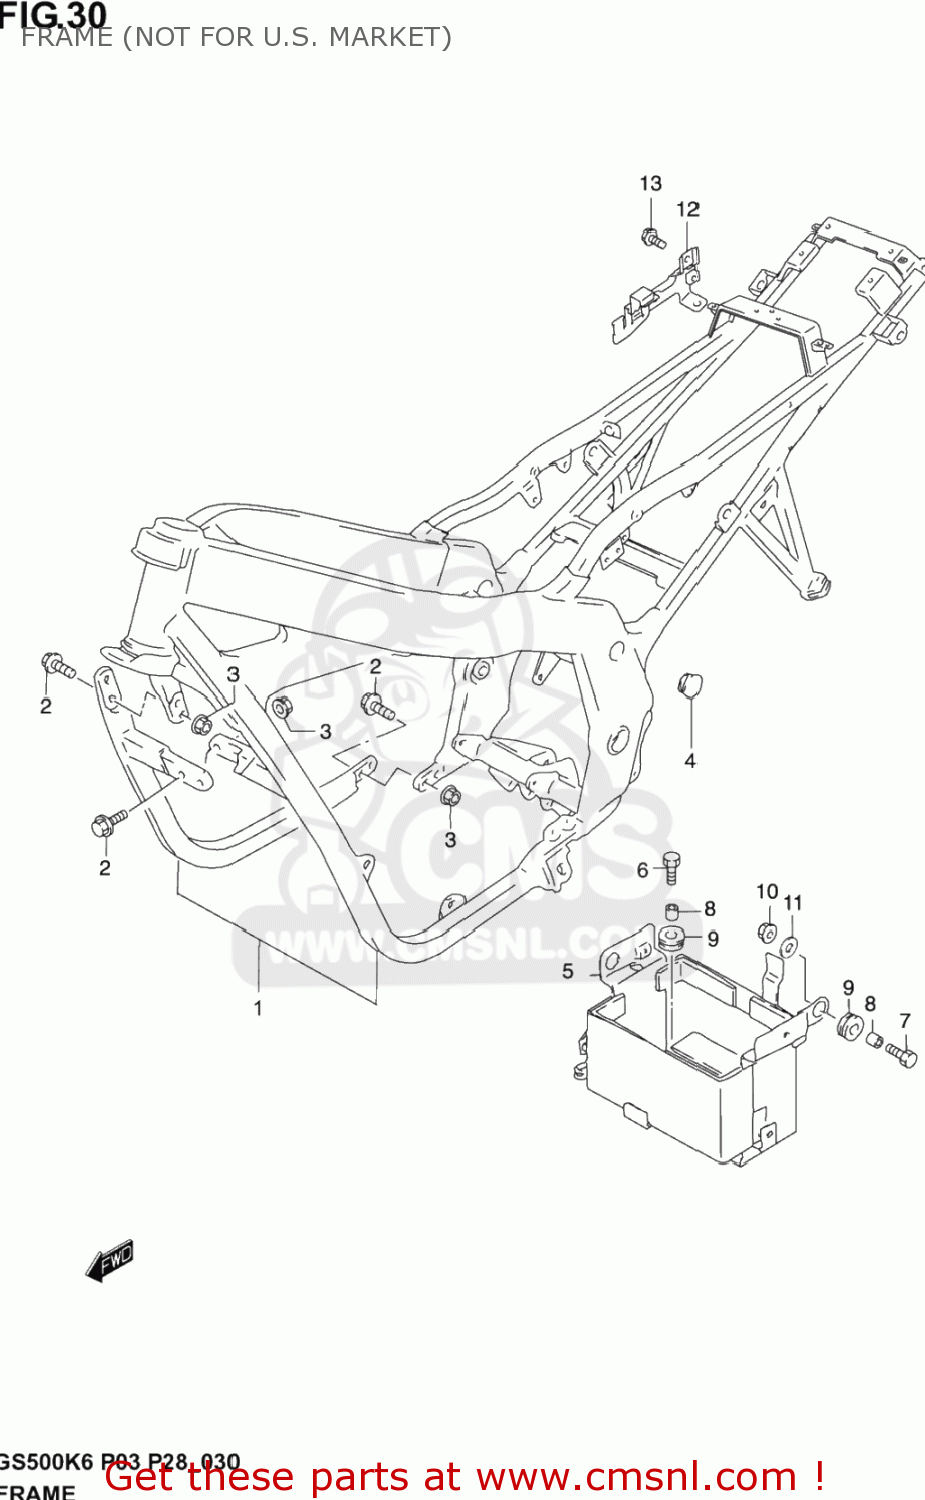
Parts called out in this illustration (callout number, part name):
1	FRAME SET(SILV
2	BOLT
3	NUT
4	CAP,BODY FRAME
5	HOLDER,BATTERY
6	BOLT 6X16
7	BOLT
8	SPACER(6.1X9X7.5)
9	CUSHION
10	NUT
11	WASHER
12	HOLDER,ELECTRIC PARTS
13	BOLT
